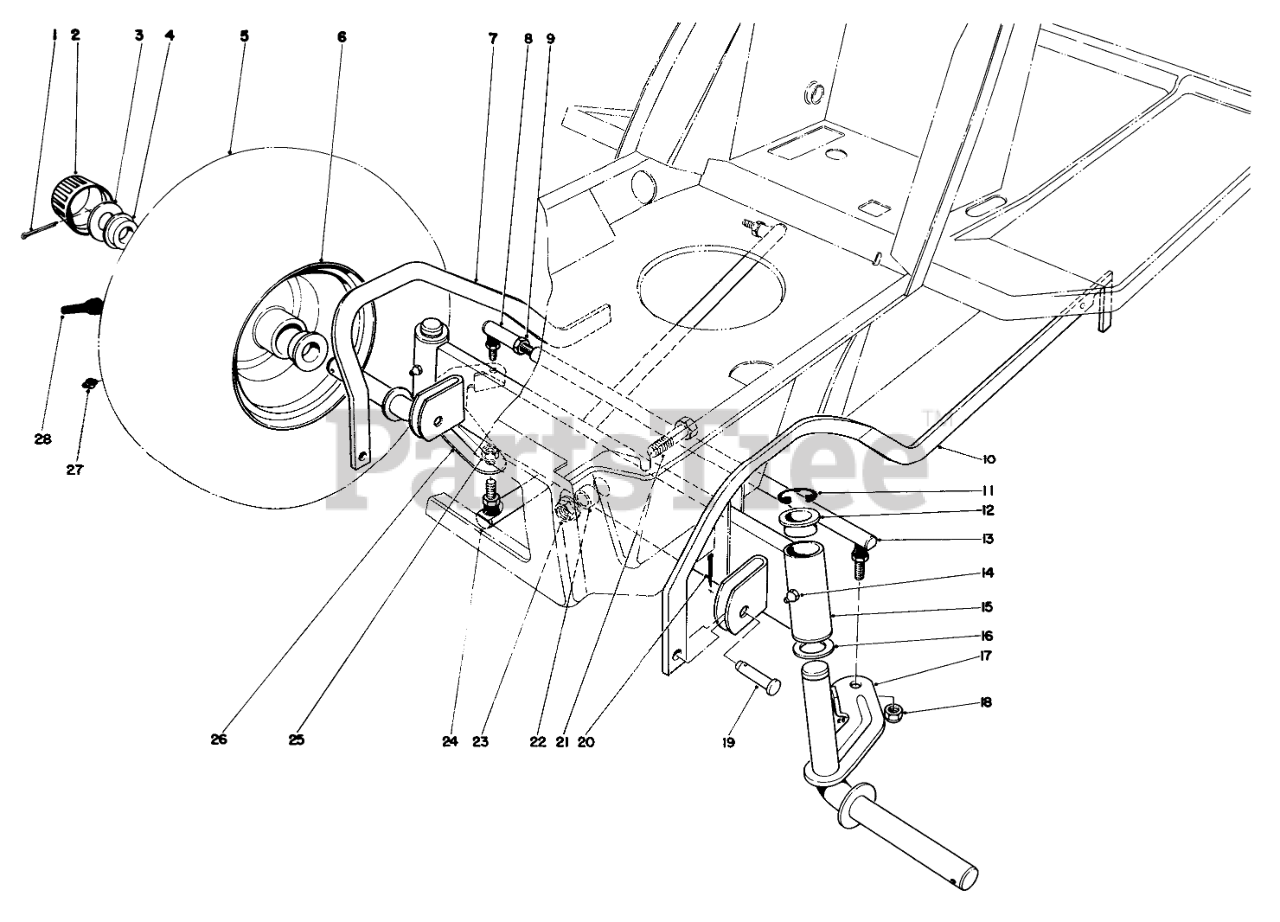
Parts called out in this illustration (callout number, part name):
1	PIN-COTTER
2	Cap-Hub
3	WASHER-PLAIN
4	Bearing
5	FRONT TIRE
6	FRONT RIM
7	R/F SCISSORS LINK WAB
8	JOINT-BALL
9	NUT-JAM
10	LF SCISSORS LINK WAB
11	E-RING
12	BEARING-FLANGE
13	STEERING ROD
14	GREASE FITTING
15	Front Axle (Incl. Ref. #10)
16	WASHER-THRUST
17	LH SPINDLE WA PP
18	NUT-LOCK, NI
19	PIN-CLEVIS
20	PIN-COTTER
21	SCREW-HH
22	SPACER-AXLE, FRONT
23	NUT-HF
24	STEERING ARM B
25	NUT-HEX
26	RH SPINDLE WA PP
27	FITTING-GREASE
28	STEM-VALVE
